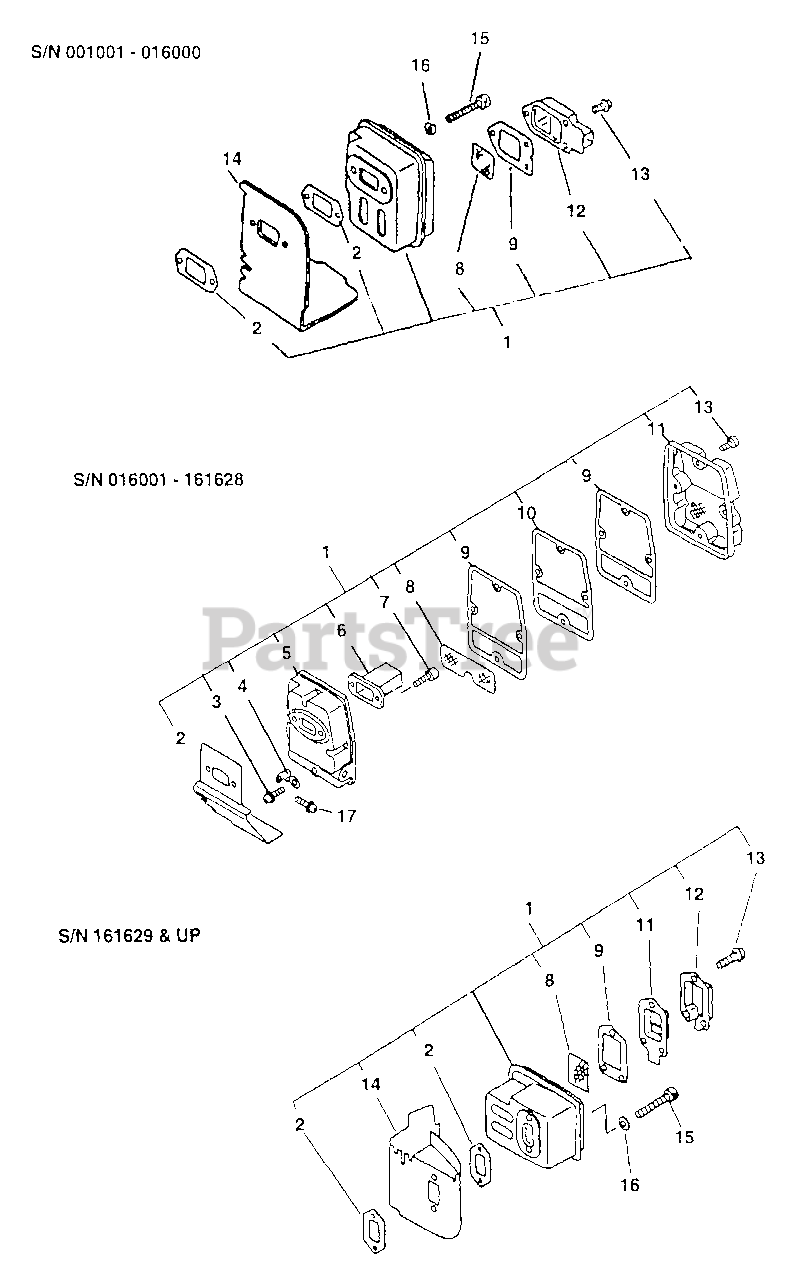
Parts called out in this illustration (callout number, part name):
1	MUFFLER ASSY
2	GASKET, EXHAUST
3	SCREW - 5X10
4	BRACKET, MUFFLER
6	BAFFLE, MUFFLER
7	SCREW - 5X18
8	SCREEN, SPARK ARRESTOR
9	GASKET, EXHAUST
10	GASKET, EXHAUST
11	LID, MUFFLER
11	GASKET, EXHAUST - INNER
12	GUIDE, EXHAUST
12	GUIDE, EXHAUST - OUTER
13	SCREW - 4X10
13	SCREW - 5X16
14	COVER, EXHAUST
15	SCREW - 5X55
16	WASHER - 5
17	SCREW - 5X14
